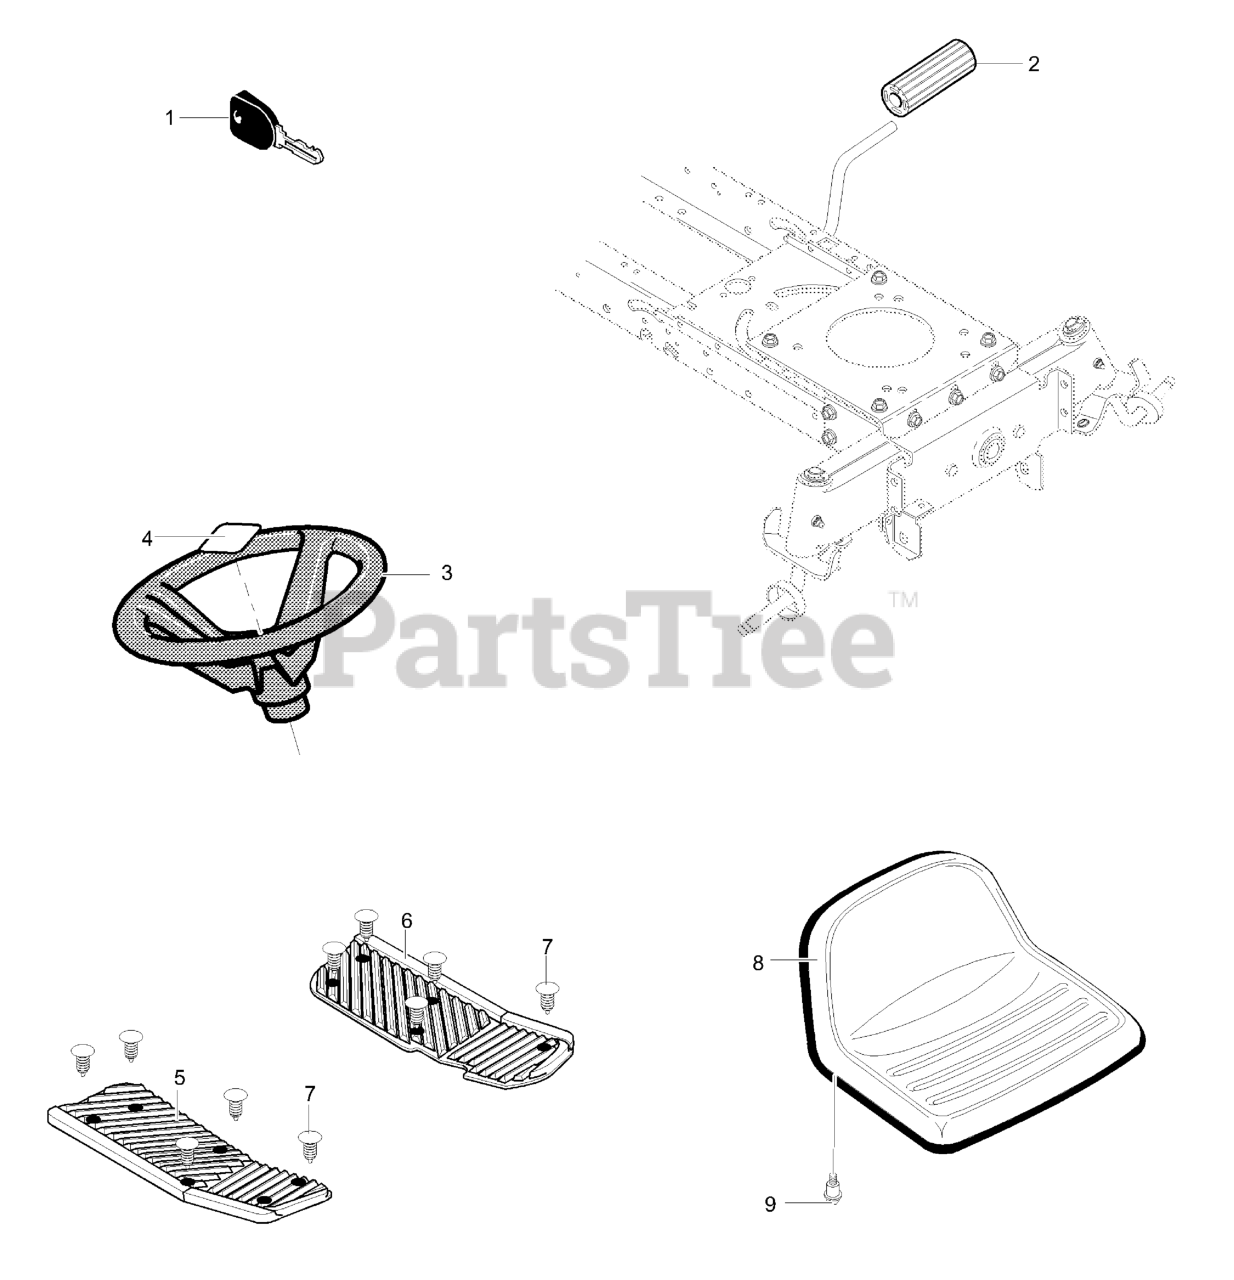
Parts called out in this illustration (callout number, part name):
1	Ignition Key
2	Cover, Pedal Brake/Clutch
3	Steering Wheel
4	Insert, 4-Spoke
5	Foot Pad RH
6	Foot Pad LH
7	Ratchet Fastener
9	Shoulder Bolt 5/16-18
